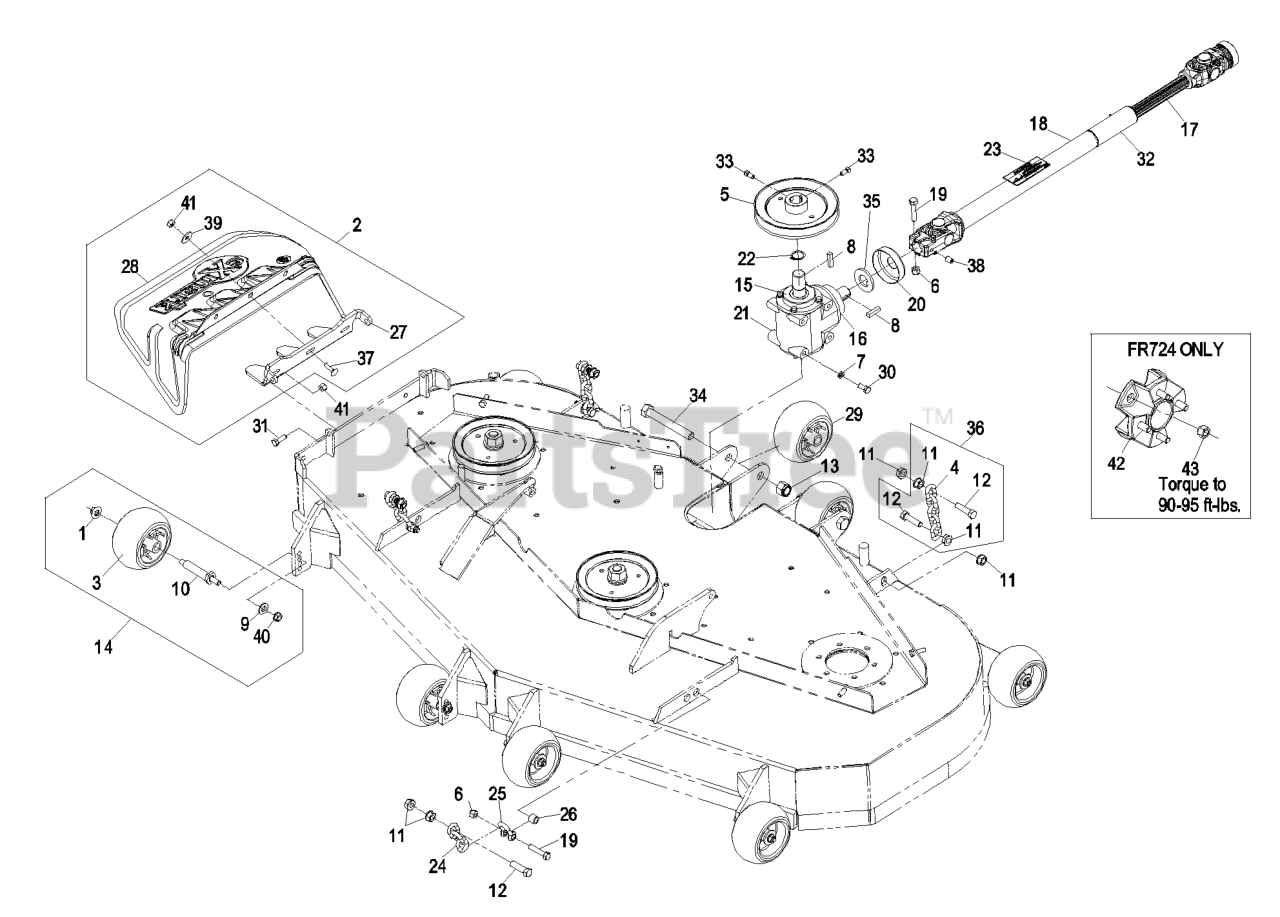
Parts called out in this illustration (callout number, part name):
1	Nut-Nyloc 3/8-16 Flg
3	ROLLER-SCALP, ANTI
4	CHAIN-LIFT, DECK
5	SHEAVE,6.88 ED B-SEC
6	NUT-LOCK, NI
7	WASHER-LOCK
8	KEY-SQUARE
9	WASHER-BELLEVILLE
12	SCREW-HH
13	NUT-LOCK, NI
19	SCREW-HH
20	GUARD,SEAL (PLTD)
21	GEARBOX,90 DEGREES
22	RING-RETAINING
23	DECAL-DRIVELINE
24	CHAIN-DECKLIFT
25	SHACKLE,FRONT CHAIN
26	BUSHING,SHACKLE
27	BRACKET,DISCHARGE CHUTE
28	CHUTE,DISCHARGE
29	ROLLER, FULL HUB
30	SCREW-HH
31	SCREW-HH
33	SCREW-SET
34	SCREW-HH
35	WASHER,SPECIAL
36	DECK CHAIN ASM
37	SCREW-CARR
38	SCREW-SET
39	WASHER-FLAT
40	NUT-HHF, WHIZ
41	NUT-LOCK, NI
42	Asm, Wheel Spacer
43	NUT-LUG
